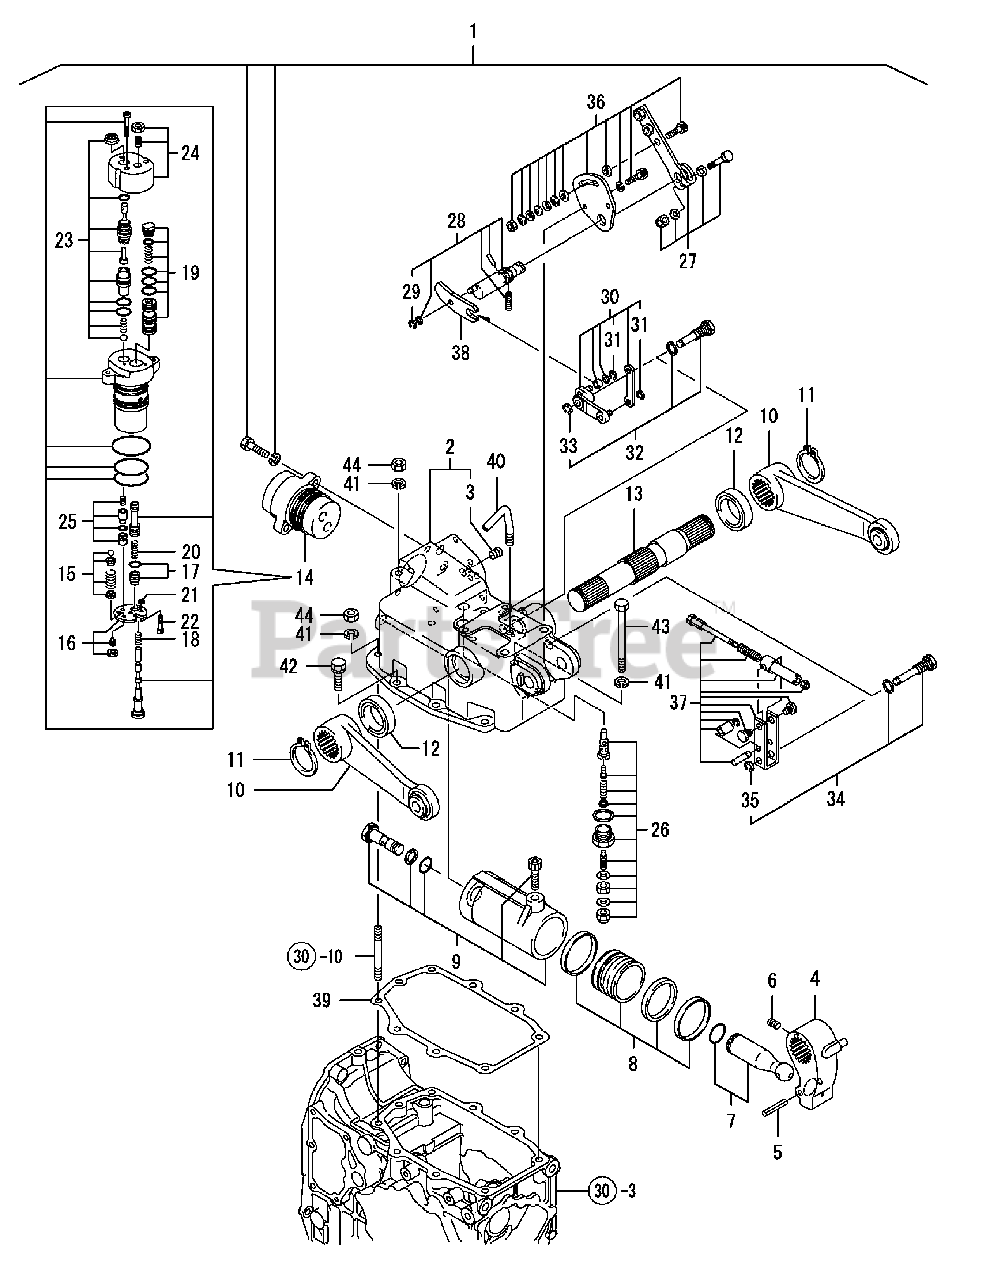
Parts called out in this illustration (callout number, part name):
1	Rock Shaft Assy
2	Case, Hydraulic Cyl.
5	Spring Pin 6X40
7	Piston Rod Comp
12	Seal, 354507 Oil
14	Valve Assy, Control
23	Lever, Cmp Slowreturn
26	Valve, Assy Relief
36	Lever, Assy Hydraulic
37	Control, Assy Hyd.
39	Packing, Cylinder
40	Pipe, Air Breather
41	Spring Washer 10
43	Bolt M10X120 Plated
